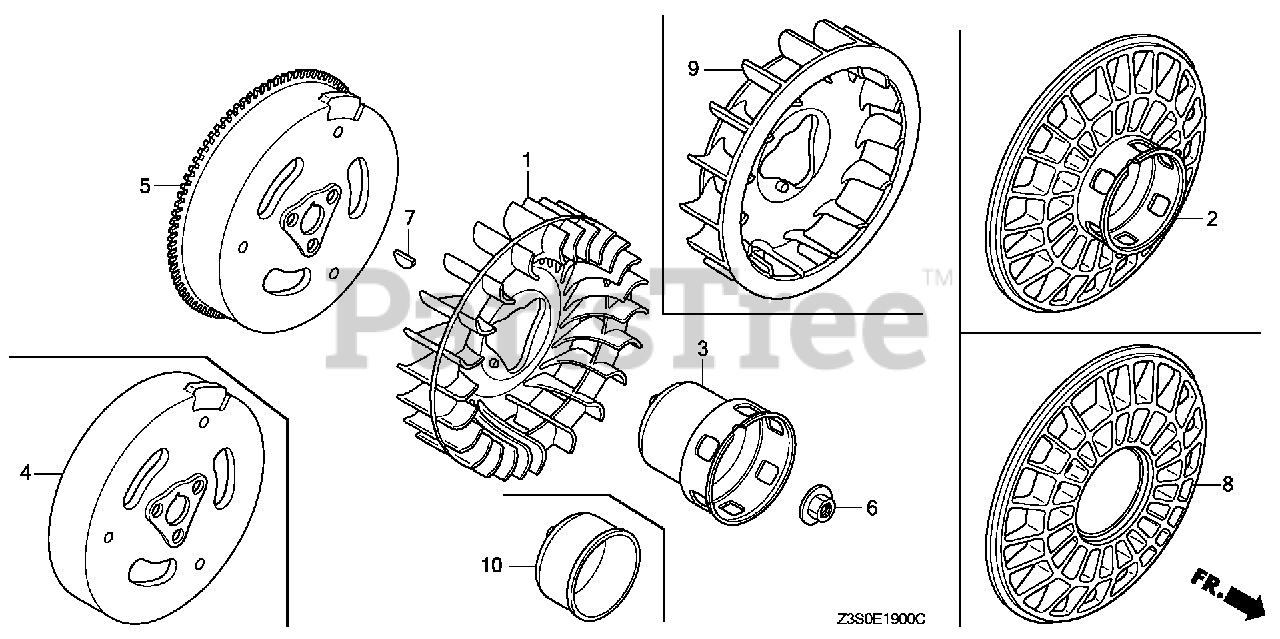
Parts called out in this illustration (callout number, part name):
3	PULLEY, STARTER
6	NUT, SPECIAL (16MM)
7	KEY, SPECIAL WOODRUFF (25X18)
9	FAN, COOLING
